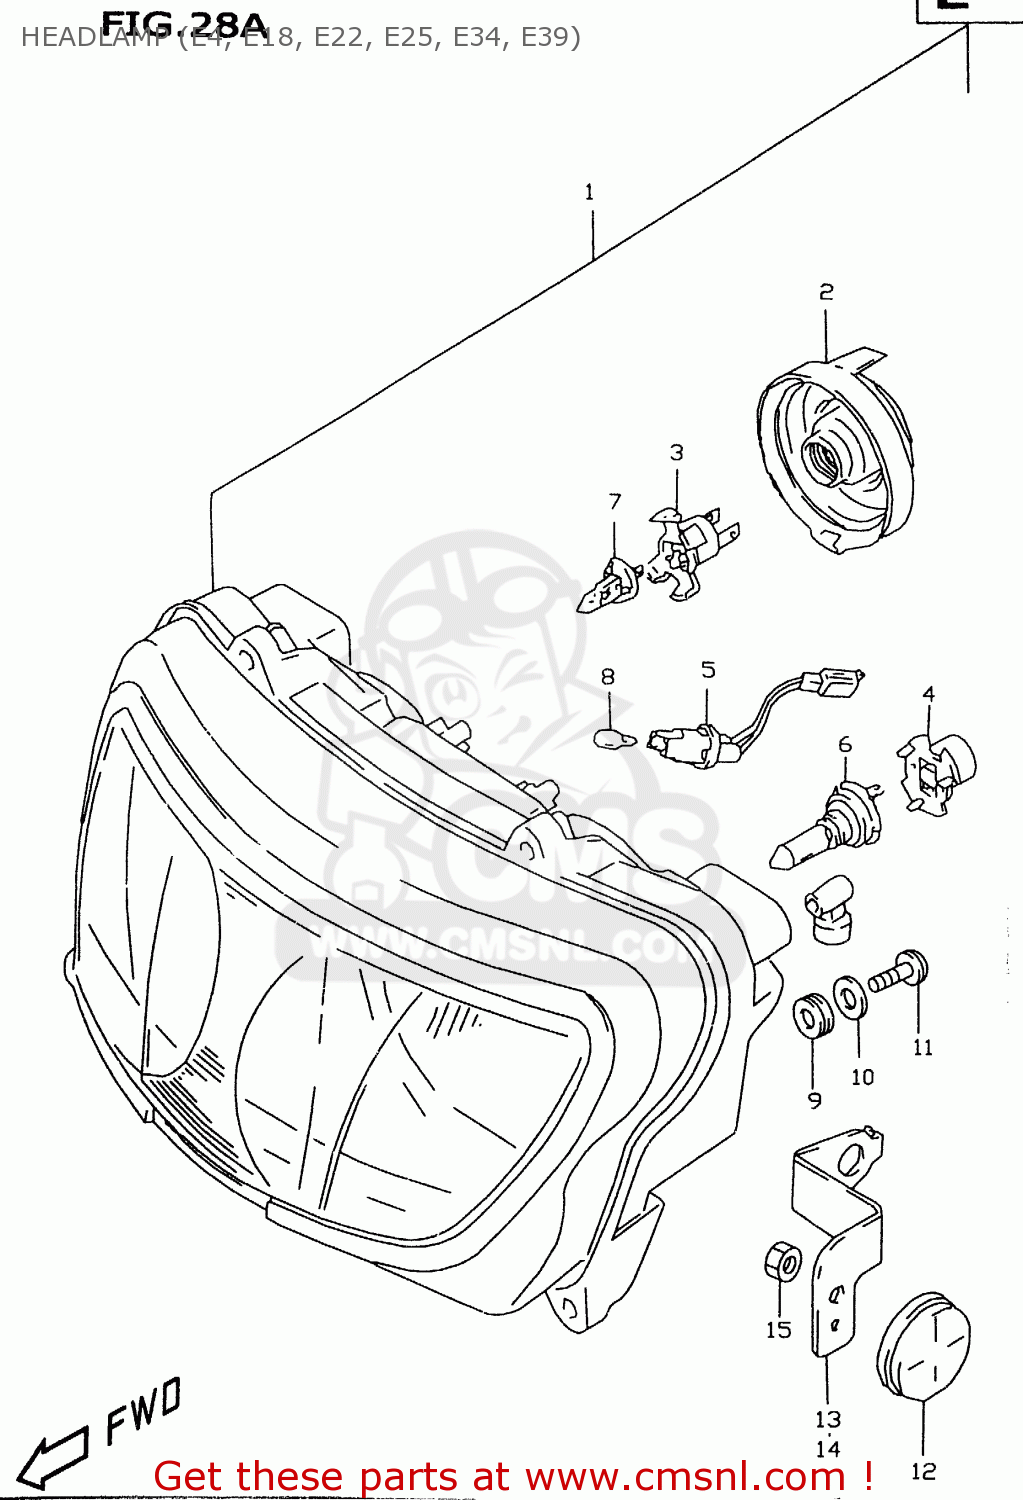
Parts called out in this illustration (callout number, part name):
1	HEADLAMP ASSY
2	COVER,SOCKET
3	ADAPTER ASSY
4	ADAPTER ASSY
5	SOCKET ASSY
6	BULB(12V55W/H7/PX26D/PHILIPS)
7	BULB(12V55W/H1/P14.5S/OSRA,PHI
8	BULB(12V5W)
9	CUSHION,HEADLAMP
10	WASHER(5.5X18X1)
11	SCREW,SIDE HOL
12	REFLECTOR,REFLEX FR
13	BRACKET,FR SIDE RR,R
14	BRACKET,FR SIDE RR,L
15	NUT
